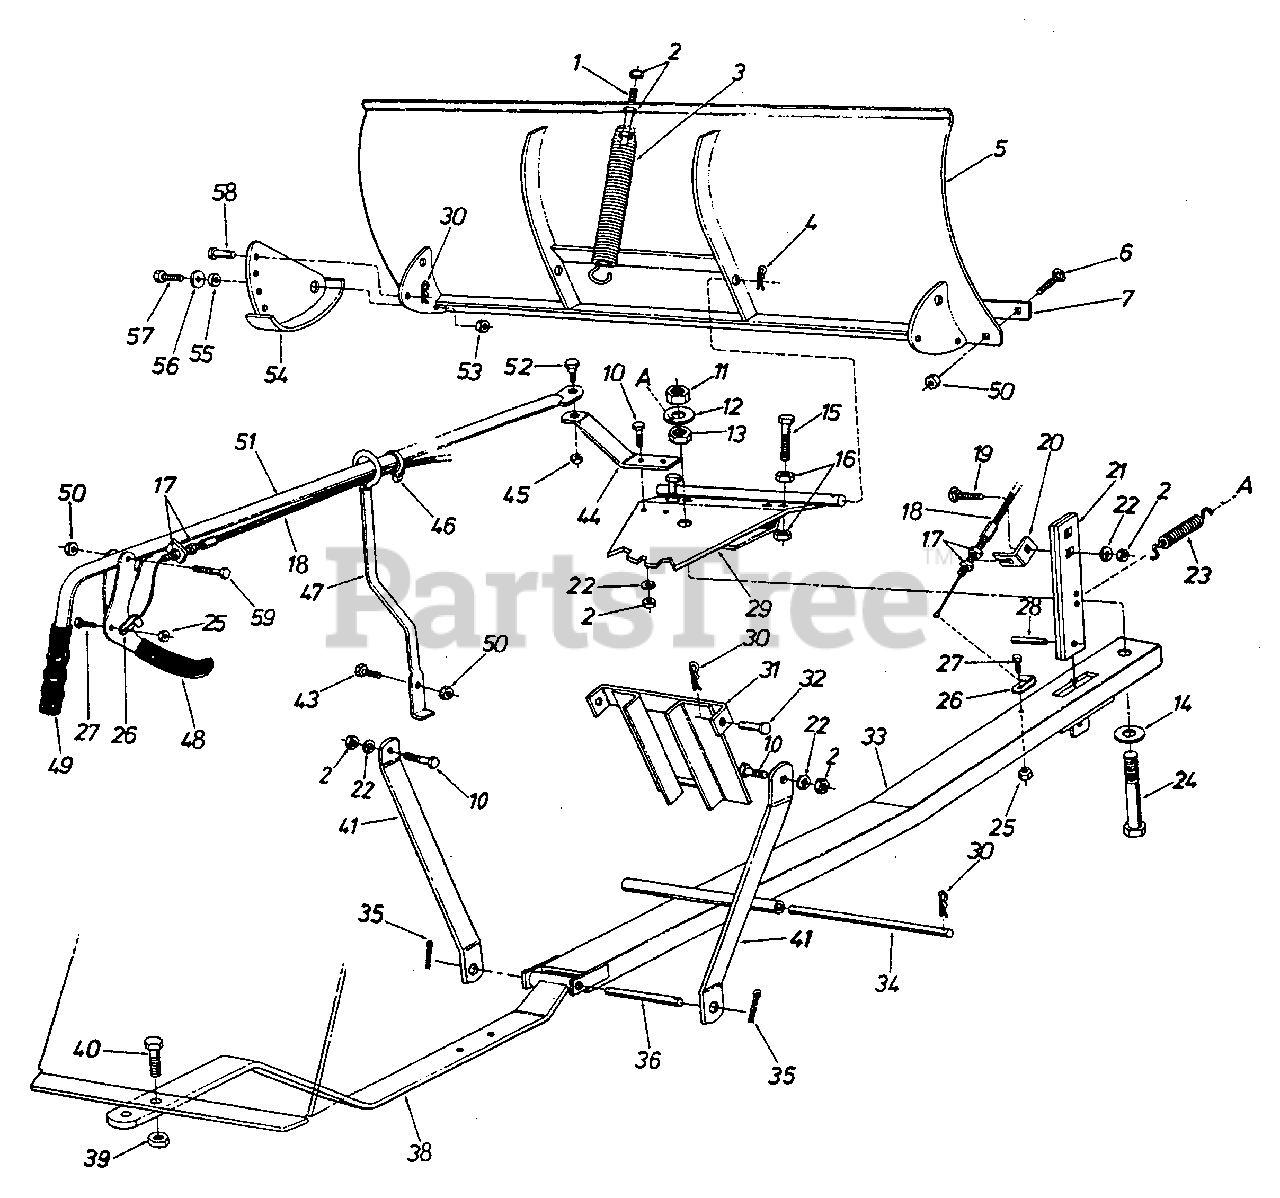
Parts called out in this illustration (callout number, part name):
1	Hex Bolt 3/8-16 x 4.5" Lg.
2	Hex Nut 3/8-16 Thd.
3	Blade Adjustment Spring
4	Hairpin Clip 5/32" Dia.
5	48" Blade Ass'y.
6	Carriage Bolt 5/16-18 x .75" Lg.
7	Wear Plate 48"
10	Hex Bolt 3/8-16 x 1.0" Lg.
11	Hex L-Nut 3/4-10 Thd.
12	Fl-Wash. .81" I.D. x 2.0" O.D. (Special)
13	Hex Jam Nut 3/4-10 Thd.
14	Fl-Wash. .81" I.D. x 2" O.D.
15	Hex Bolt 1/2-13 x 2.0" Lg.
16	Hex Nut 1/2-13 Thd.
17	Hex Jam Nut 5/16-24 Thd.
18	Control Cable Ass'y.
19	Carriage Bolt 3/8-16 x 1.25" Lg.
20	Cable Guide Bracket
21	Angle-Lock Bar
22	L-Wash. 3/8" I.D
23	Angle Lock Spring
24	Hex Scr. 3/4-10 x 4.0" Lg.
25	Hex L-Nut 1/4-20 Thd.
26	Clevis Lanyard Fitting
27	Hex Bolt 1/4-20 x .75" Lg.
28	Roll Pin 1/4" Dia. x 1.0" Lg.
29	Pivot Plate Ass'y.
30	Hairpin Clip 3/32" Dia.
31	Guide Bracket Ass'y.
32	Clevis Pin 1/2" Dia. x 1.0" Lg.
33	Push Bar Ass'y.
34	Lift Shaft
35	Cotter Pin 5/32" Dia. x 1.0" Lg.
36	Pivot Shaft
38	Hanger Bracket Ass'y.
39	Hex L-Nut 5/8-11 Thd.
40	Hex Bolt 5/8-11 x 1.5" Lg.
41	Hanger Link
43	Hex Bolt 5/16-18 x 1.0" Lg.
44	Blade Pivot Bracket
45	Hex L-Nut 3/8-16 Thd.
46	Nylon Cable Tie
47	Tube Guide Ass'y.
48	Clutch Grip Ass'y.
49	Grip-3/4" Handle
50	Hex L-Nut 5/16-18 Thd.
51	Tube Handle Ass'y.
52	Shld. Bolt-Special 3/8-16 Thd.
53	Hex L-Nut 3/8-16 Thd.
54	Skid Assembly
55	Spacer
56	Fl-Wash. .385" I.D. x 1.0" O.D.
57	Hex Bolt 3/8-16 x 4.75" Lg.
58	Clevis Pin 5/16" Dia. x .75" Lg.
59	Hex Bolt 5/16-18 x 1.5" Lg.
